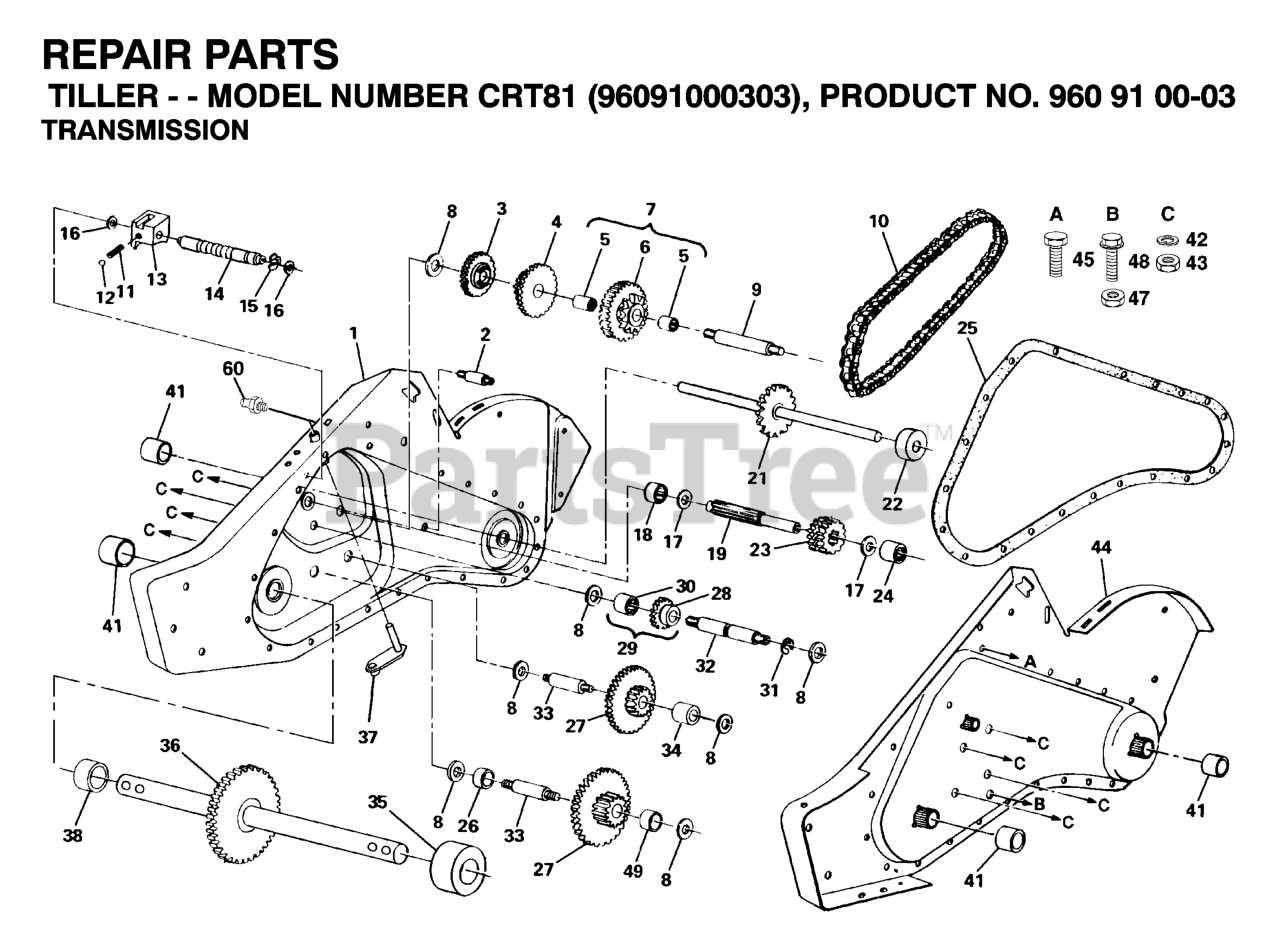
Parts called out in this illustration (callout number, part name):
1	GEARCASE ASM.RH.W/BEARING 2002
2	SPACER.GEARCASE
3	GEAR.REVERSE.8HP
5	BEARING.NEEDLE.CRT
6	SPROCKET ASMBLY, TINE
7	SPROCKET ASMBLY W/BEARINGS
9	SHAFT.REDUCTION.TILLER
10	CHAIN.ROLLER.TILLER
11	SPRING-SHIFT CRT
12	STEEL BALL KIT
13	SHIFT FORK TI
14	SHAFT.SHIFT.1.00 PINION
16	WASHER, SEAL (2 2)
17	THRUST WASHER
18	BEARING TI
19	SHAFT INPUT
21	SHAFT TINE CRT
22	SPACER 1.008X1-3/4X.645
23	GEAR.PINION
24	NEEDLE BRNG LT
25	RP GASKET, GEARCASE
27	GEAR, CLUSTER CRT
28	REVERSE GEAR
29	GEAR ASMBLY, REVERSE IDLER
30	NEEDLE BEARING TI
32	SHAFT, REVERSE IDLER
33	SHAFT, REDUCTION
34	SPACER.765 X 1.12 X .380.
35	SPACER, GROUND DRIVE RH
36	SHAFT ASSY CRT
37	BRACKET ASM.SHIFT.CRT
38	SPACER, GROUND DRIVE
41	SEAL ASM, OIL
42	LOCKWASHER
43	NUT.ASF.HEX.7/16
44	GEARCASE ASM.LH.W/BEARING 2002
45	SCREW
48	SCREW 5/16-18X4
60	FITTING.GREASE.TAPERED
